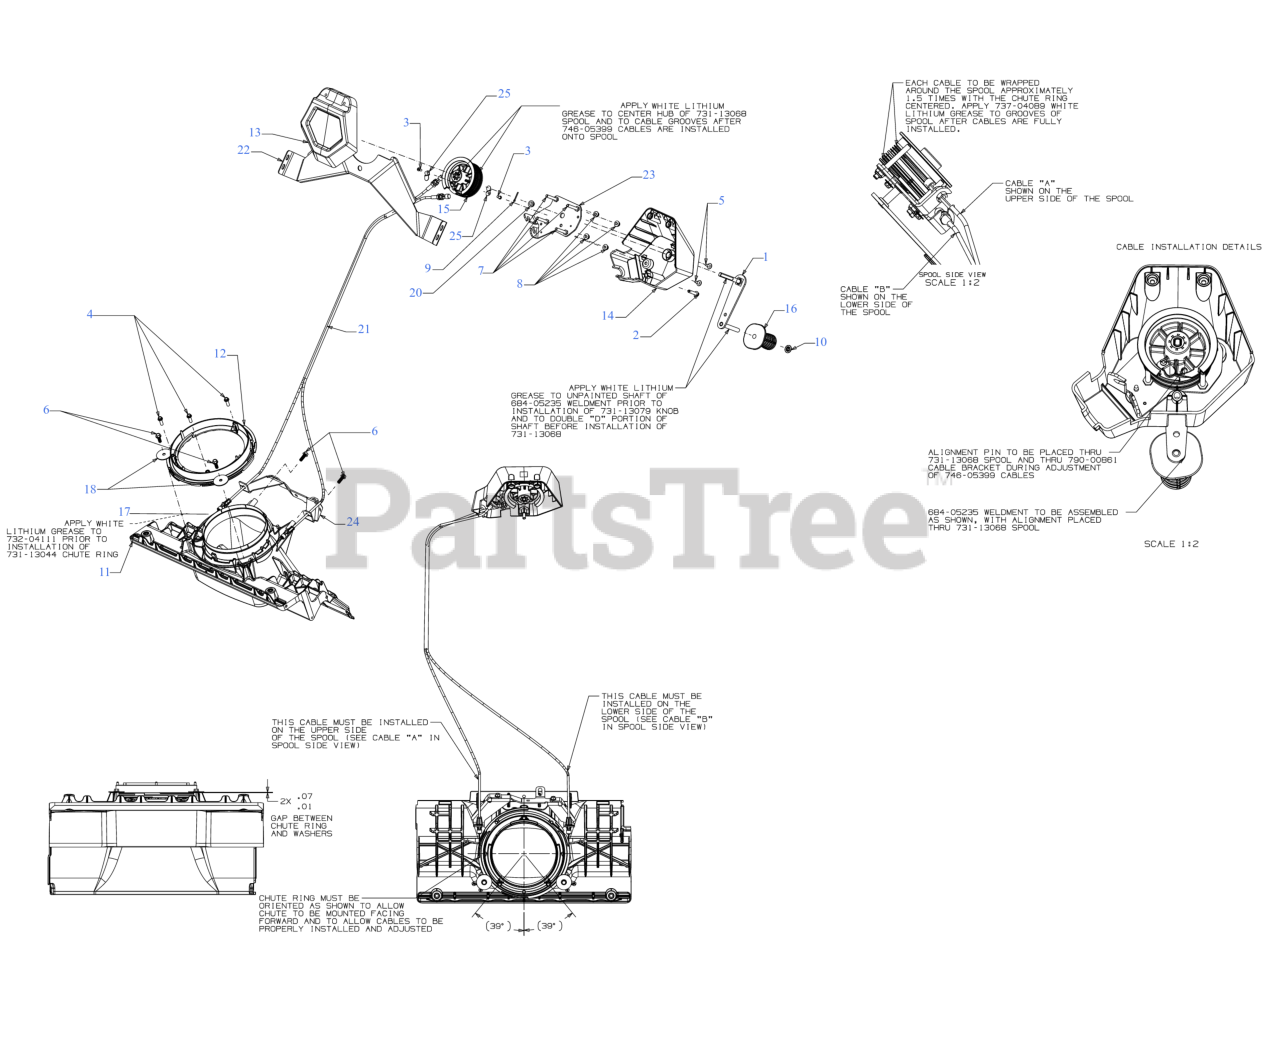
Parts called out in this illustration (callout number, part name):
1	CHUTE ROTATION CRANK (POWDER BLACK)
2	SCREW 1/4-15 x 1.250
3	SCREW 8-16 x .375" T20
4	SCREW 1/4 x .750
5	SCREW M6-1 x .625
6	SCREW 1/4-15 x .750
7	CABLE KEEPER
8	FLANGE LOCK NUT
9	COTTER PIN-3/32 DIA x .75
10	PUSH NUT
11	CHUTE ADAPTER
12	CHUTE CABLE CONTROL RING
13	UPPER CONTROL HOUSING
14	LOWER CONTROL HOUSING
15	CHUTE CABLE SPOOL
16	CHUTE CRANK KNOB
17	CHUTE ADJUSTMENT SPRING
18	FLAT WASHER
20	FLANGE BEARING
21	CHUTE ROTATION CABLE
22	HANDLE PANEL CHUTE ROTATION
23	CHUTE ROTATION BRACKET
24	CHUTE CRANK BRACKET
25	CABLE CLIP
